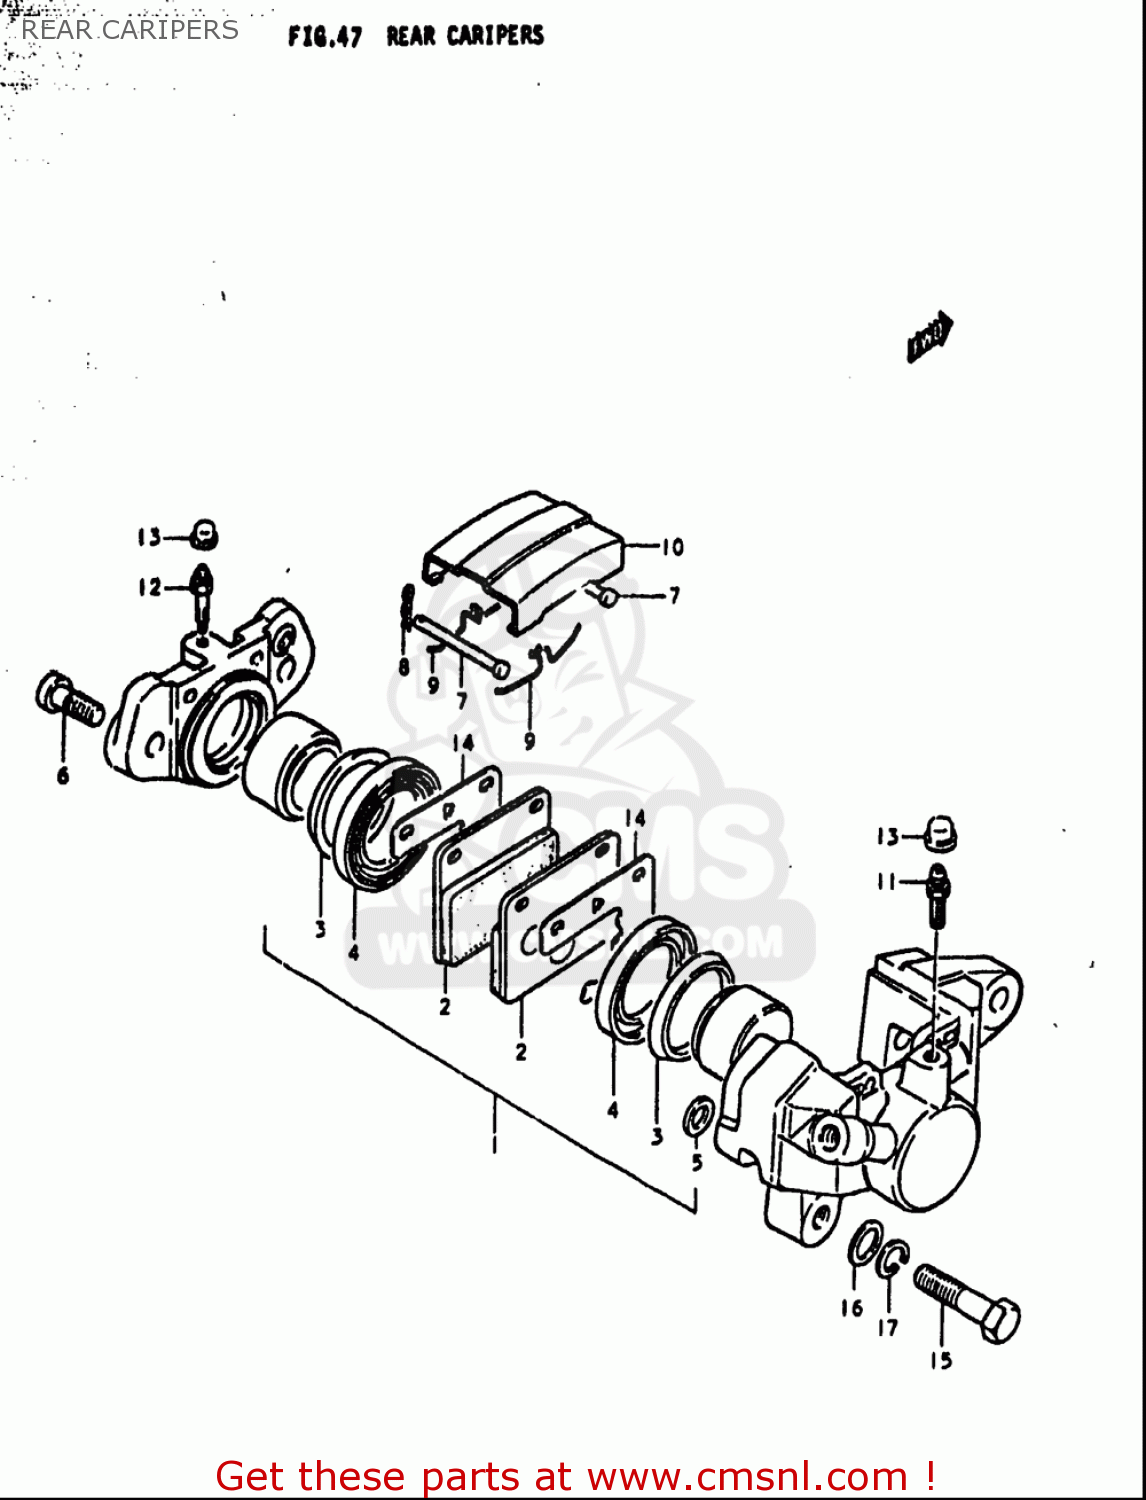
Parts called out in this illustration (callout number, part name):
1	PISTON SET
2	PAD SET (NAS)
3	SEAL,PISTON
4	BOOT,PISTON
5	SEAL,PISTON
6	BOLT,HOUSING
7	PIN,PAD
8	CLIP,PAD PIN
9	SPRING
10	COVER,DUST
11	BLEEDER
13	CAP,BLEEDER PLUG
14	SHIM,RR CALIPER
15	BOLT(10X34)
16	WASHER
17	WASHER,LOCK
